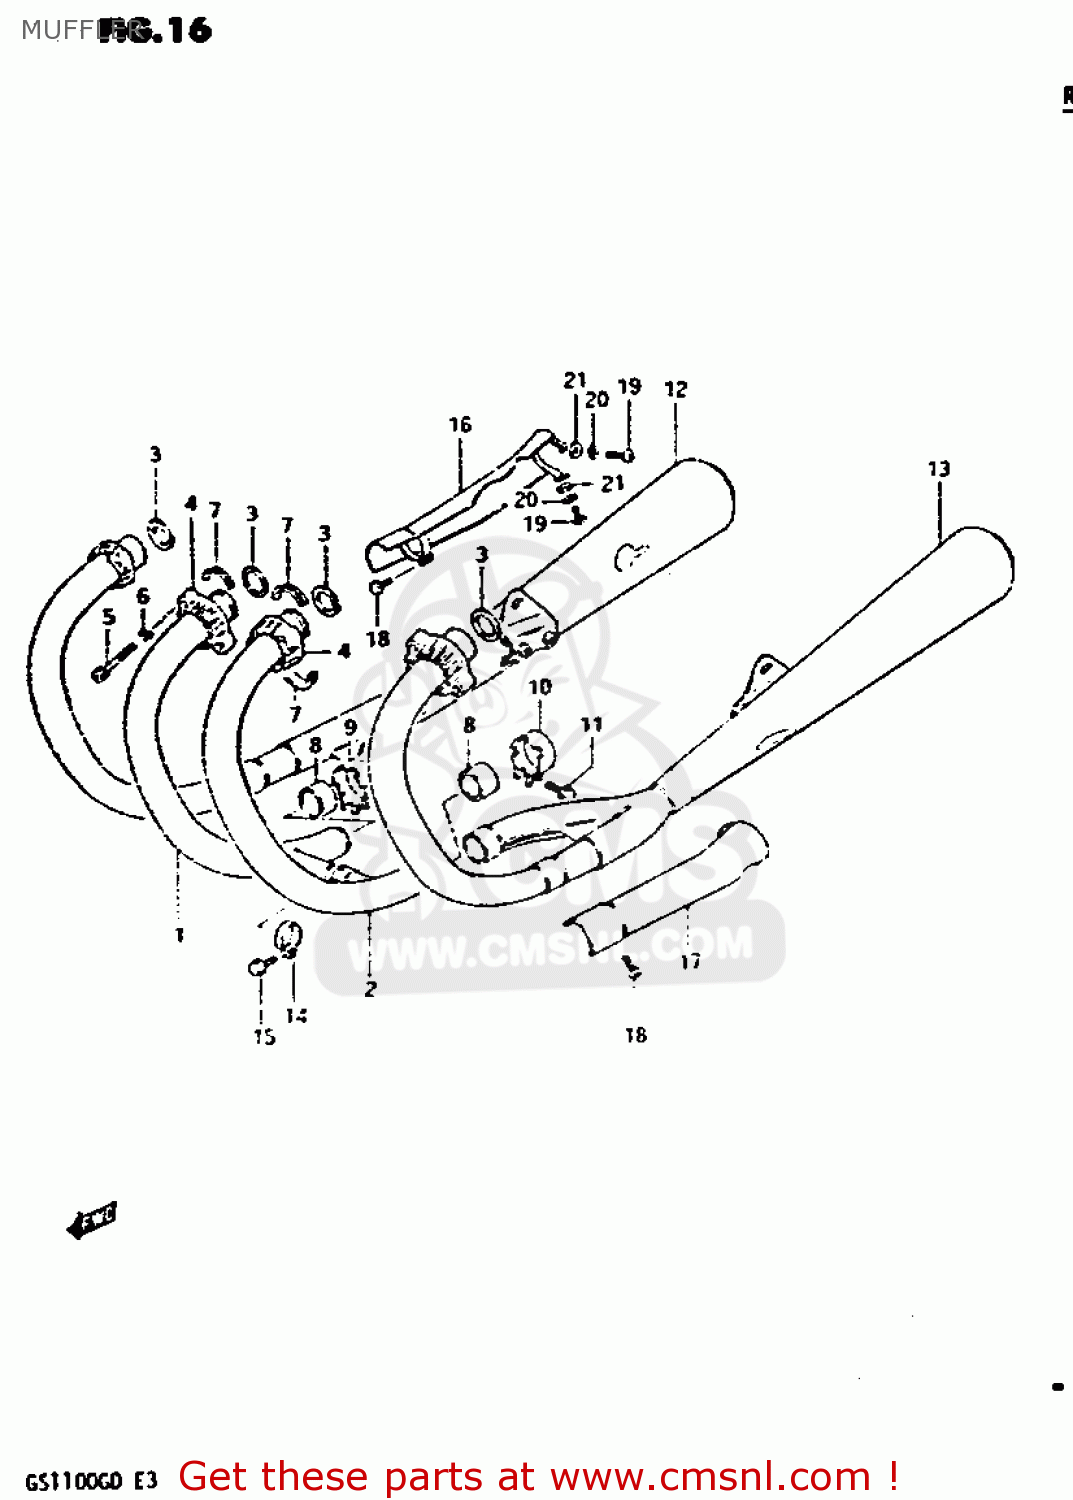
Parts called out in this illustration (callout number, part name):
1	PIPE,EXHAUST,CENTER,RIGHT
2	PIPE,EXHAUST,CENTER,LEFT
3	GASKET,EXHAUST PIPE (NAS)
4	CLAMP(H:21)
5	BOLT
6	LOCK WASHER
7	PLATE,EXHAUST P
8	CONNECTOR,MUFFLER
9	CLAMP,MUFFLER CONNECTOR,R
10	CLAMP,MUFFLER CONNECTOR,L
11	BOLT
12	MUFFLER,R
13	MUFFLER,L
14	CLAMP
15	BOLT 6X25
16	COVER,MUFFLER,RIGHT
17	COVER,MUFFLER,LEFT
18	SCREW
19	SCREW
20	WASHER,LOCK
21	WASHER
